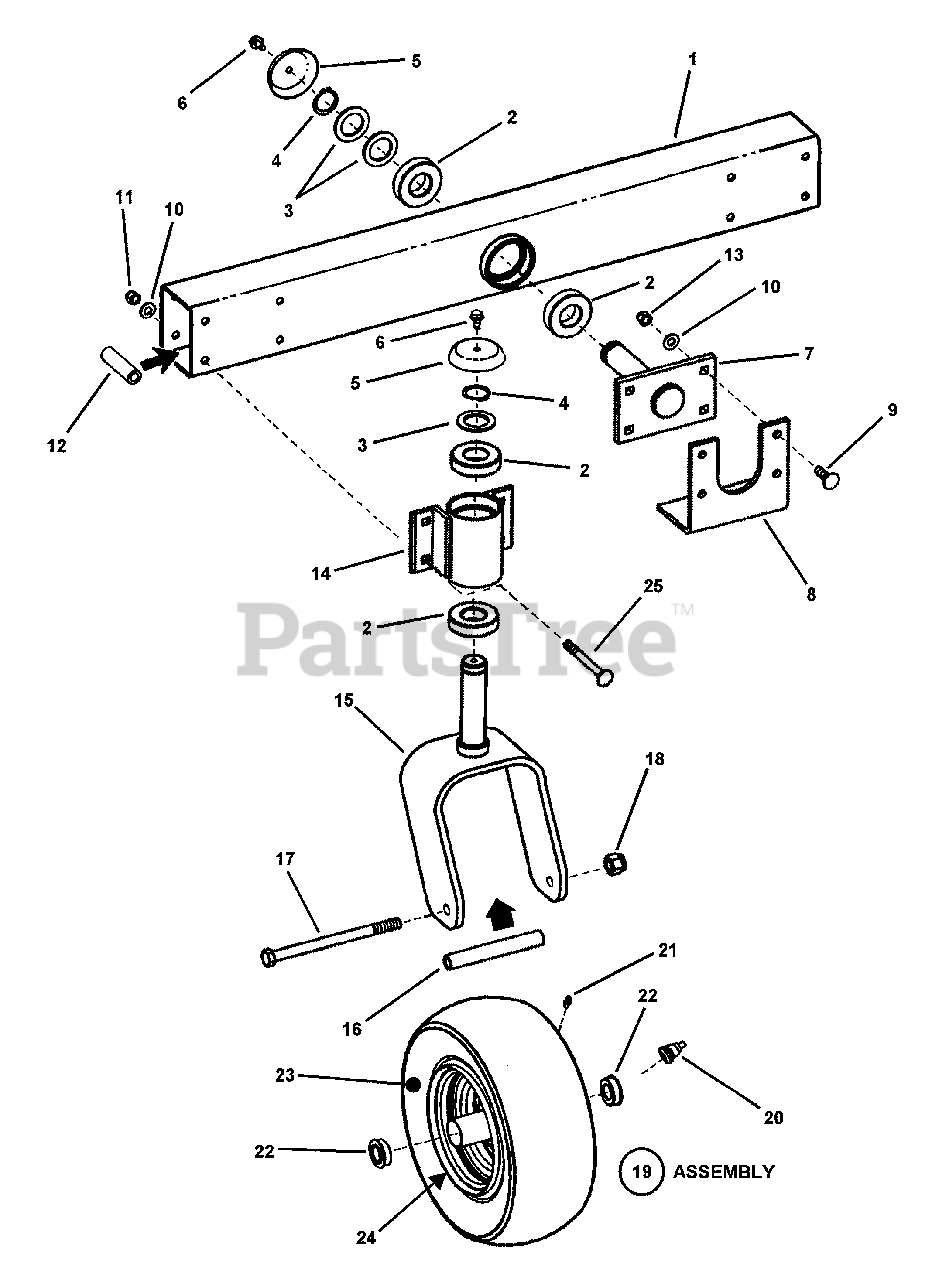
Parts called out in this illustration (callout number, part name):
1	WELDMENT, Axle
2	BEARING, 30mm x 62mm
3	WASHER, 1-1/4 I.D. x 1-7/8" O.D. Flat
4	RING, 1-3/16 External Retaining
5	CAP, Caster Shaft
6	SCREW, 5/16-18 x 5/8" Self-Tapping
7	WELDMENT, Front Axle Pivot
8	BRACKET, Axle Stop
9	BOLT, 3/8-16 X 1-1/2" Short Neck Carriage, Grade 5
10	WASHER, 3/8" Flat
11	NUT, 3/8-16 HEX NYLON LOCK
12	TUBE, 13/32 I.D. x 3/4 O.D. x 2.70
13	NUT, 3/8-16 Hex Center Lock, Grade B or 5
14	WELDMENT, Caster Support
15	WELDMENT, Caster Yoke
16	SPACER, Bearing
17	BOLT, HEX, 1/2-13 X 7, GD 8, YZ
18	NUT, 1/2-13 Nyloc
19	ASSEMBLY, Tire & Rim
20	VALVE, Air
21	FITTING, Lube
22	BEARING
23	TIRE, 13 x 5.00-6, 4 Ply
25	BOLT, 3/8-16 x 4" Square Neck Carriage, Grade 5
